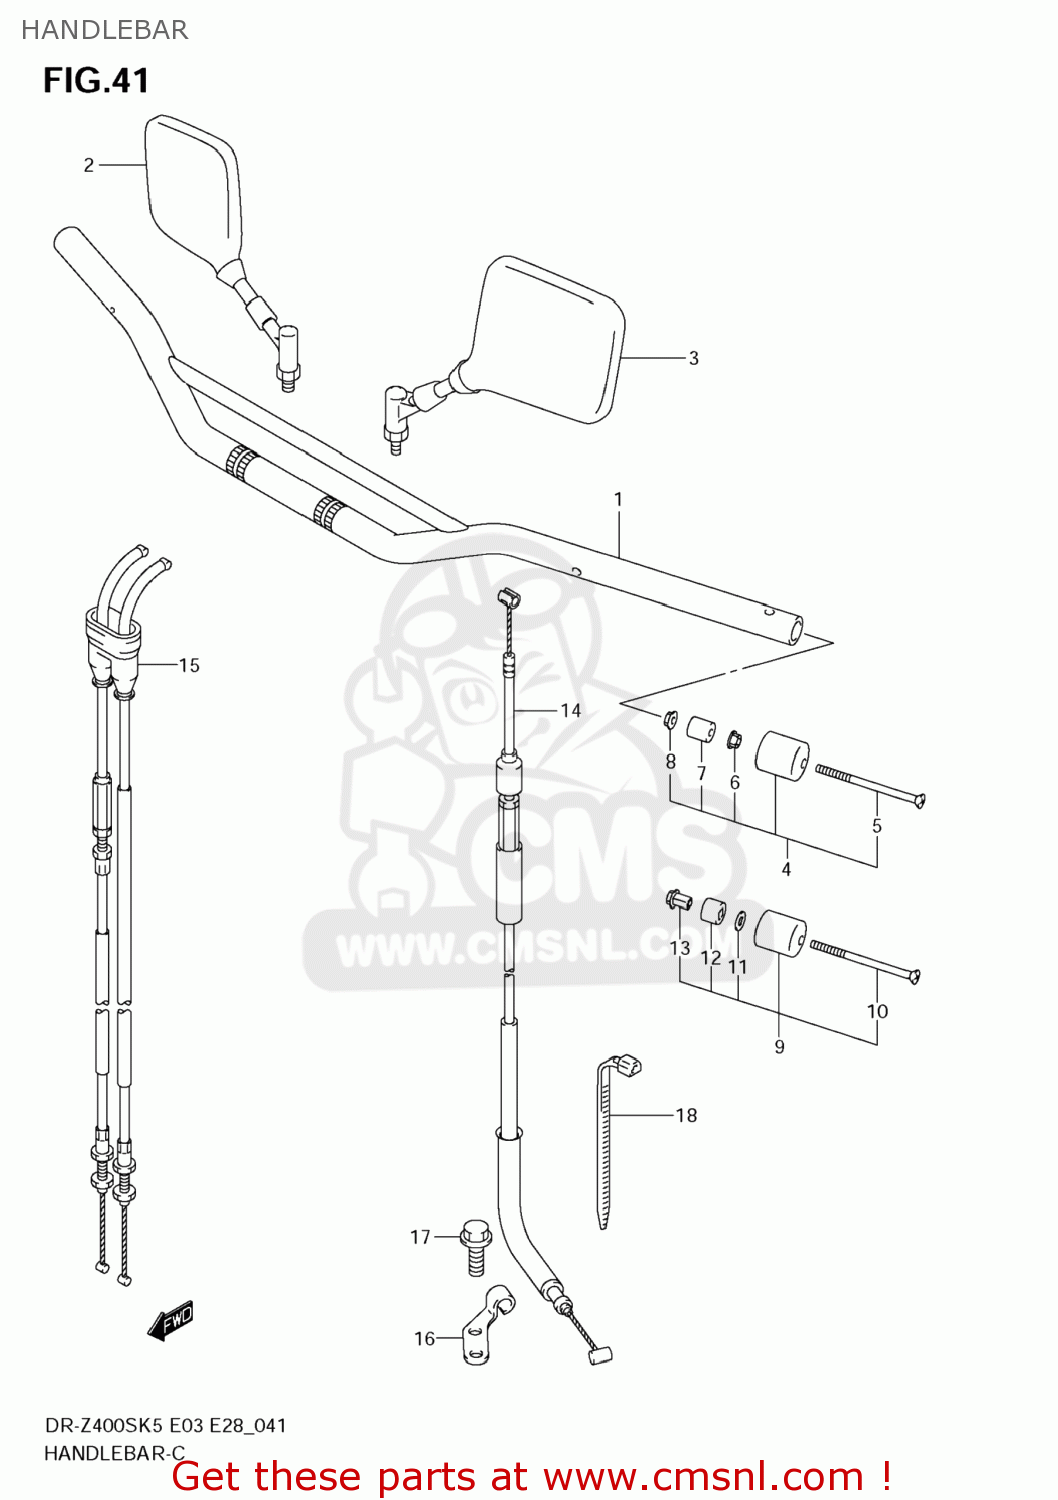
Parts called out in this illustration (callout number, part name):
1	HANDLEBAR(SILVER)
2	MIRROR ASSY,RR VIEW,R
3	MIRROR ASSY,RR VIEW,L
4	BALANCER SET,HANDLEBAR
5	SCREW
6	NUT
7	EXPANDER,HANDLE BALANCER
8	NUT
9	BALANCER SET,HANDLEBAR
10	SCREW
11	WASHER(6.5X16X4)
12	EXPANDER,HANDLE BALANCER
13	NUT,HANDLE BALANCER
14	CABLE ASSY,CLUTCH
15	CABLE SET,THROTTLE
16	STOPPER,CLUTCH CABLE
17	BOLT
18	CLAMP(L:145)
